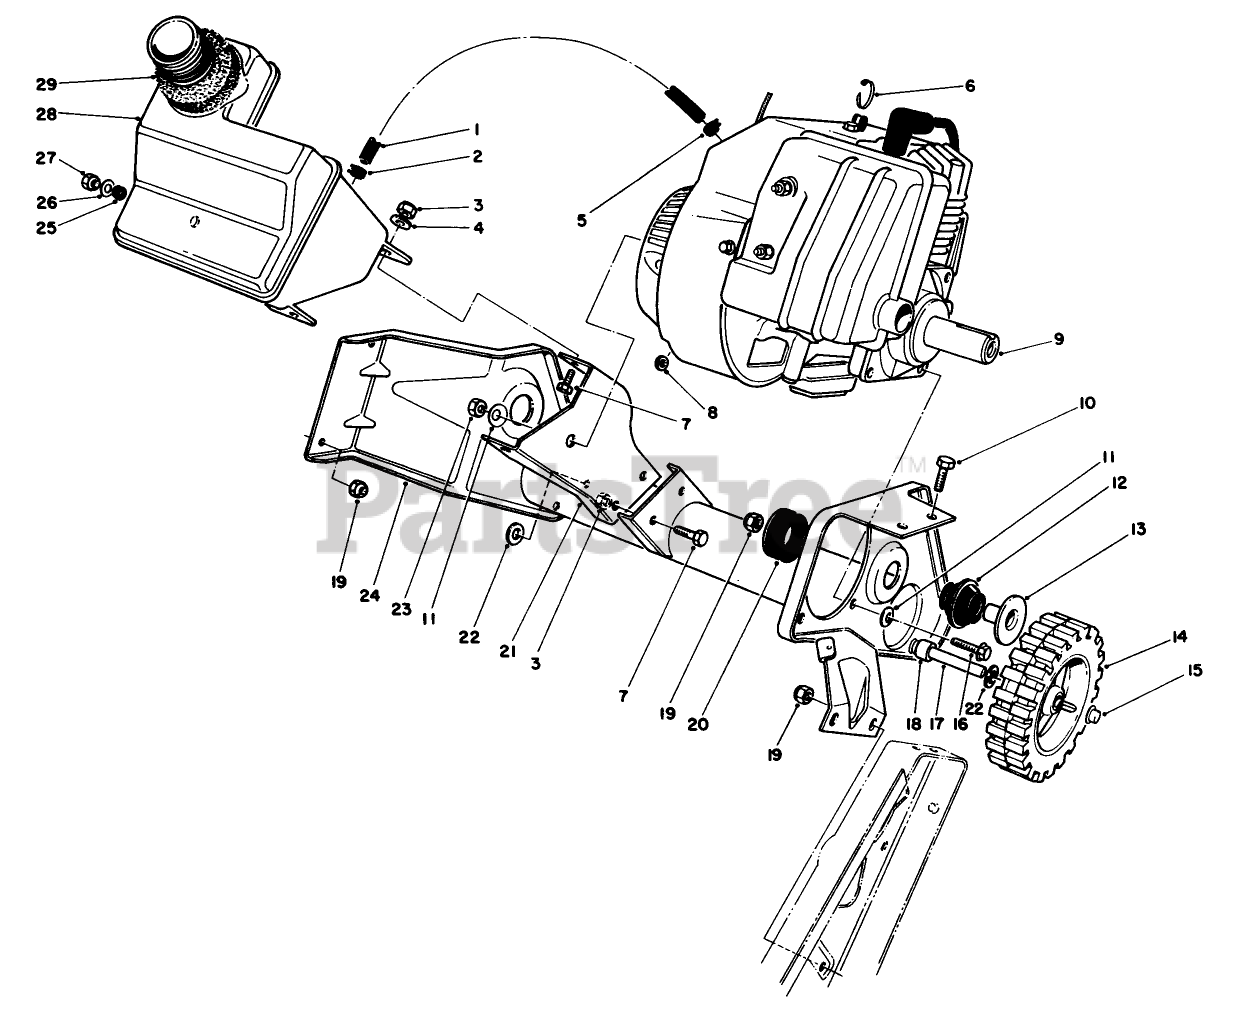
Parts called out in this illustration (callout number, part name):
1	GasLine
2	Clamp
3	NUT-LOCK, NI
4	WASHER-FLAT
5	CLAMP-HOSE
6	TIE-CABLE
7	SCREW-HH
8	SPACER-PLATE, PIVOT
9	Engine Assembly
10	SCREW-HH
11	WASHER-BELLEVILLE
12	MOUNT-REBOUND
13	SPACER TUBE
14	WHEEL
15	RETAINER-PUSH ON
18	WHEEL SPACER
19	NUT-LOCK, NI
20	LOAD MOUNT
21	Support-Recoil
22	WASHER-FLAT
23	NUT (F/W & PPP)
24	Frame Assembly
25	GROMMET-RUBBER
26	WASHER-PLAIN
27	NUT-LOCK, CONE
28	Tank-Fuel (Incl. Ref. #25)
29	SEAL-FOAM
